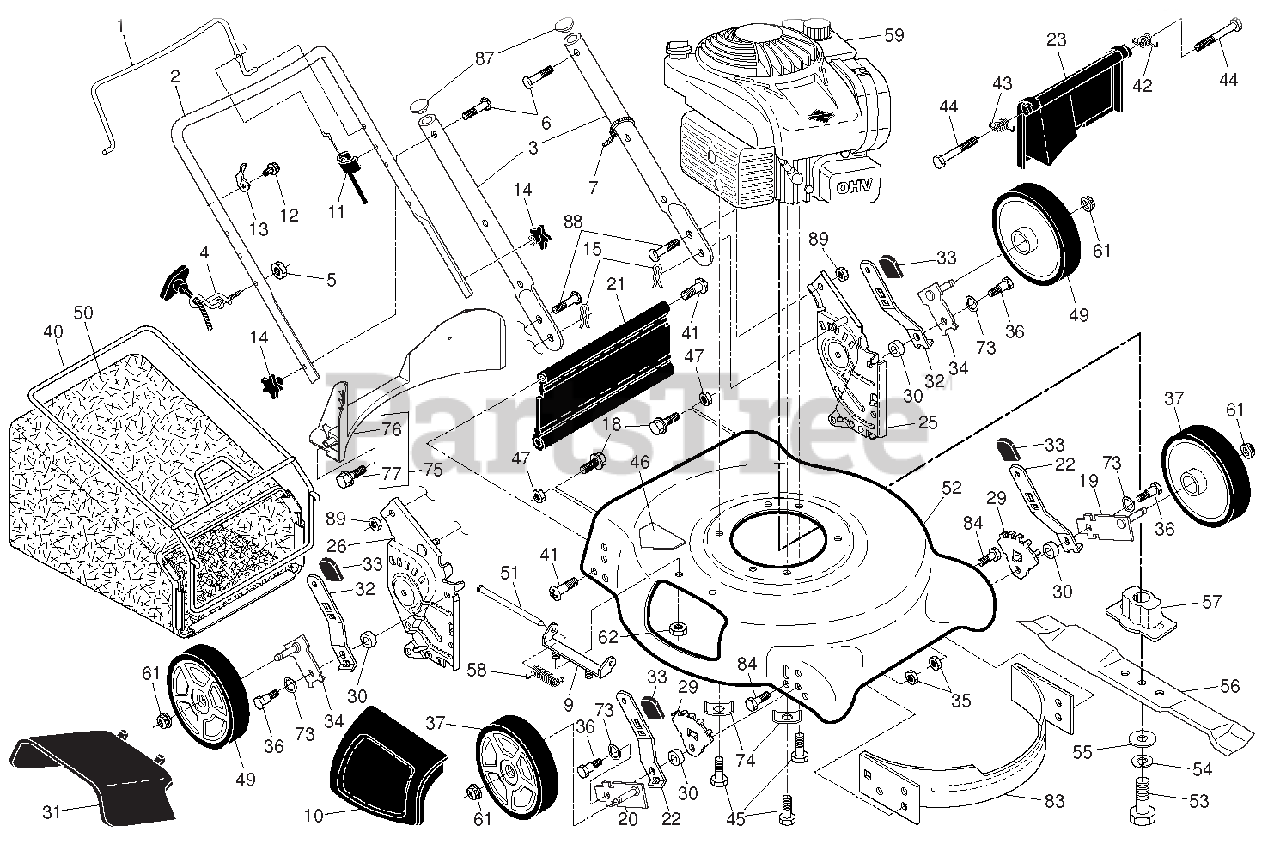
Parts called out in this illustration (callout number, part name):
1	CONTROL BAR
2	UPPER HANDLE
3	BAR, LOWER HANDLE
4	Rope Guide
5	Nut, Hex
6	Handle Bolt
7	Wire Tie
9	Hinge Bracket
10	Mulcher Door
11	ENGINE ZONE CONTROL CABLE
12	SCREW, HEX WASHER HEAD
13	UP-STOP BRACKET
14	Handle Knob
15	Hairpin Cotter
18	SCREW.HEX.WASHEAD.1/4-20 X 3/8
19	Axle Arm Assembly, Front, LH
20	Axle Arm Assembly, Front, RH
21	Kit, Rear Skirt
22	Selector Spring, Front
23	Rear Door Assembly
25	HANDLE BRACKET ASSEMBLY, LH
26	HANDLE BRACKET ASSEMBLY, RH
29	WHEEL ADJUSTING BRACKET, FRONT
31	Discharge Deflector
32	SELECTOR SPRING, REAR
33	Selector Knob
34	AXLE ARM ASSEMBLY, REAR
35	Locknut, Hex 5/16-18
36	Shoulder Bolt
37	WHEEL & TIRE ASSEMBLY
40	Frame, Grassbag
41	HINGE SCREW
42	Spring, Rear Door, LH
43	Spring, Rear Door, RH
44	Bolt, Rear Door
45	Screw, Hex Head, Threaded, Rol
46	Danger Decal
47	NUT.CENTER LOCK.5/16-18 UNC
49	WHEEL & TIRE ASSEMBLY
50	Grassbag
51	Hinge Rod
52	KIT, LAWN MOWER HOUSING
53	Screw, Hex Head, Grade 8 3/8-2
54	Helical Lockwasher
55	Hardened Washer
56	21" Blade
57	BLADE ADAPTER
58	Hinge Spring
61	Nut, Hex
62	Locknut, Hex 1/4-20
73	Washer, Curved, Cylindrical
74	Washer, Special, Engine
75	Kit, Rear Baffle (Includes 3 S
76	Baffle, Rear
77	Screw, Rear Baffle
83	BAFFLE, FRONT
84	BOLT.5/16-18HEX.WHS.HD.LCKSERR
87	PLUG, HANDLE BAR
88	BOLT, CARRIAGE 5/16-18 X 5/8
89	Nut, Hex, Flangelock
